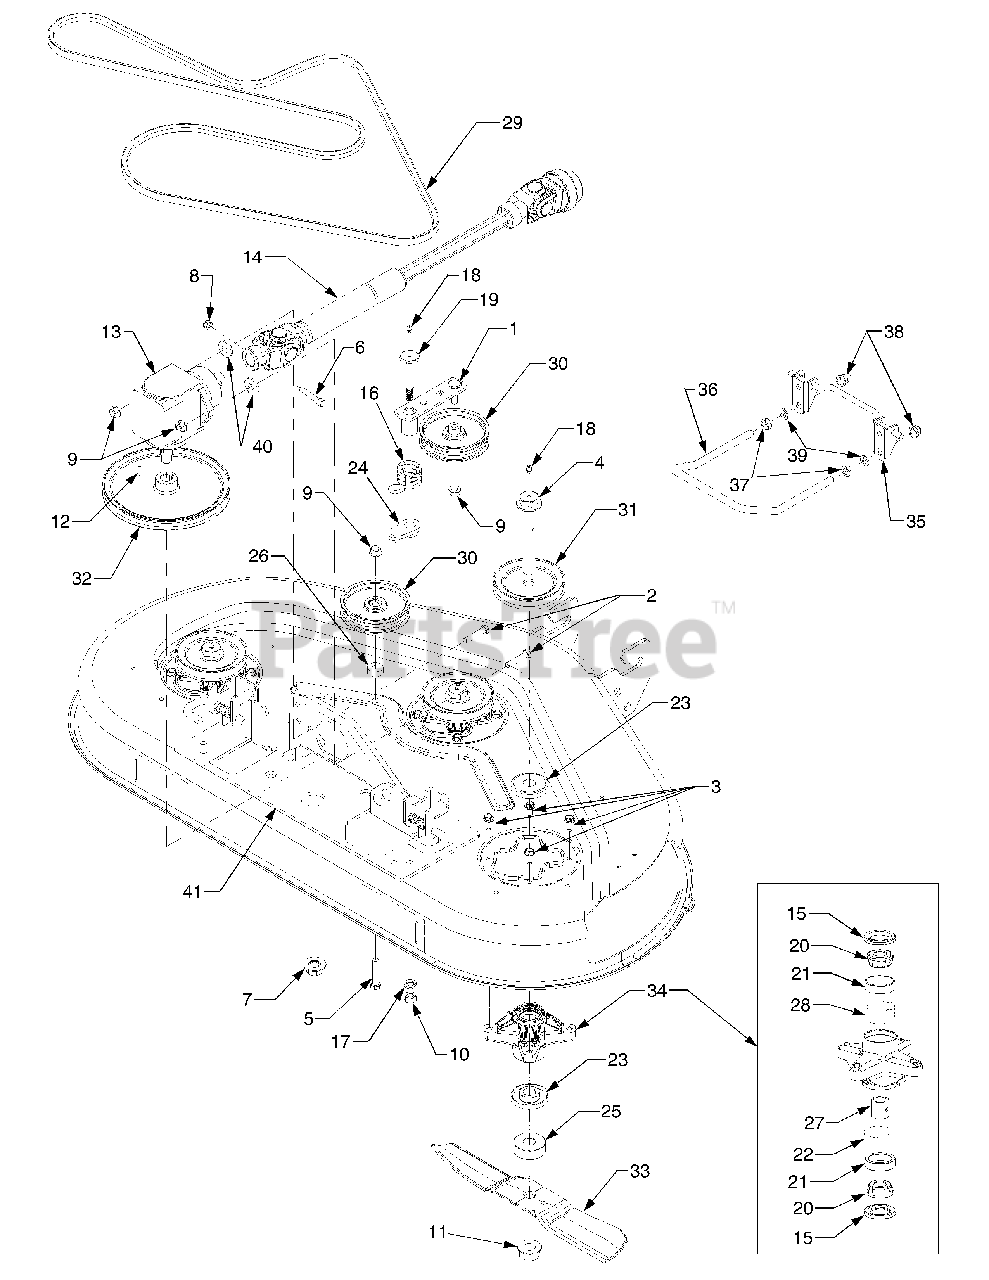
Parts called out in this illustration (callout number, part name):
1	Arm Assembly, Idler yellow
2	Screw, Hex Cap, 3/8-16 x 1.75 GR5
3	Screw, Hex Wash. Hd. Tapp 5/16-18 x .75
4	Bolt, Spindle, 3/4-16 x 5.37
5	Screw, Hex Cap, 3/8-16 x 2.0 GR5
6	Screw, Socket Hd. 5/16-18 x 1.75
7	Nut, Hex Flange, 5/8-18
8	Nut, Hex Nylon Lock, 5/16-18
9	Nut, Hex Flange Lock, 3/8-16
10	Nut, Hex, 7/16-14
11	Nut, Hex Flange, 3/4-16
12	Key, Hi Pro, 3/16 x 3/4
13	Drive, Right Angle
14	Shaft, Drive
15	Seal, Oil
16	Spring, Idler Torsion
17	Washer, Lock, 7/16
18	Fitting, Lube, 3/16 Drive
19	Screw, Shoulder, .68 x 2.11
20	Bearing, Cone - Mfg. Code 1I173G and before
20	Bearing, Cone - Mfg Code 1I183G and after
21	Cup, Bearing - Mfg. Code 1I173G and before
21	Cup, Bearing - Mfg. Code 1I183G
22	Spacer, Bearing
23	Spacer, Spindle
24	Retainer, Spring
25	Spacer, Blade
26	Spacer, .406 x 1.0 x .38
27	Spacer, Bearing - Mfg. Code 1I173G and before
27	Spacer, Bearing - Mfg. Code 1I183G and after
28	Spacer, Bearing
29	Belt, ‘V’
30	Pulley, Flat Idler
33	Blade, Mower, 15.94 Long
34	Assembly, Spindle - Replaces all older spindles.
35	Bracket, Front Lift
36	Rod, Front Lift
37	Nut, Hex Jam 5/8-11
38	Nut, Hex Lock 5/8-11
39	Washer, Lock 5/8" I.D.
40	Washer, Flat, .385 x 1.0 x .135.
41	Bracket Assembly, Mounting
